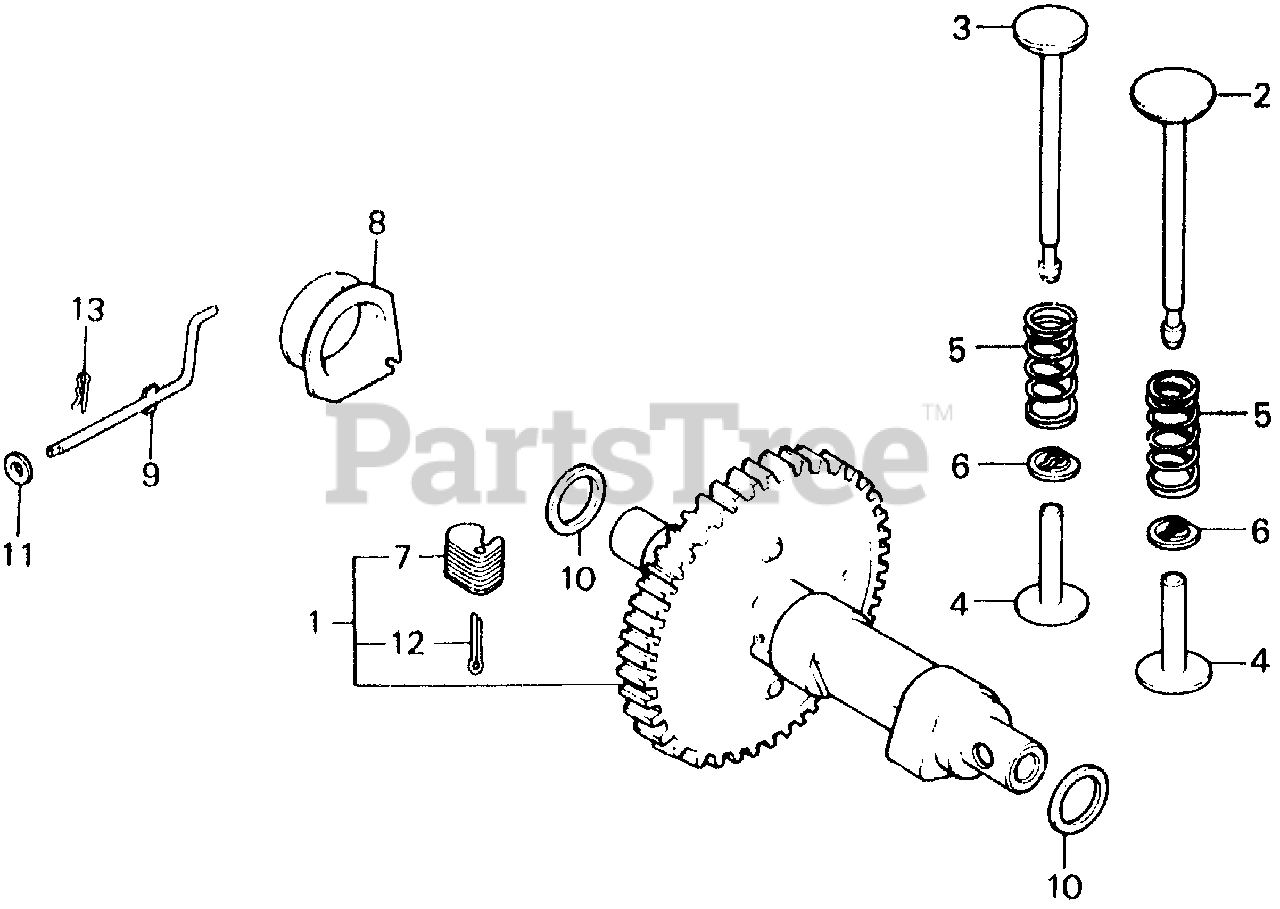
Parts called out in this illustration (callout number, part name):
1	CAMSHAFT ASSY.
2	VALVE, IN.
3	VALVE, EX.
4	LIFTER, VALVE (34.39)
4	LIFTER, VALVE (34.66)
5	SPRING, VALVE
6	RETAINER, VALVE SPRING
7	WEIGHT, GOVERNOR
8	SLIDER, GOVERNOR
9	SHAFT, GOVERNOR ARM
10	WASHER, THRUST (18MM)
11	WASHER, PLAIN (5MM)
12	PIN, COTTER (3.0X45)
13	PIN, LOCK (8MM)
